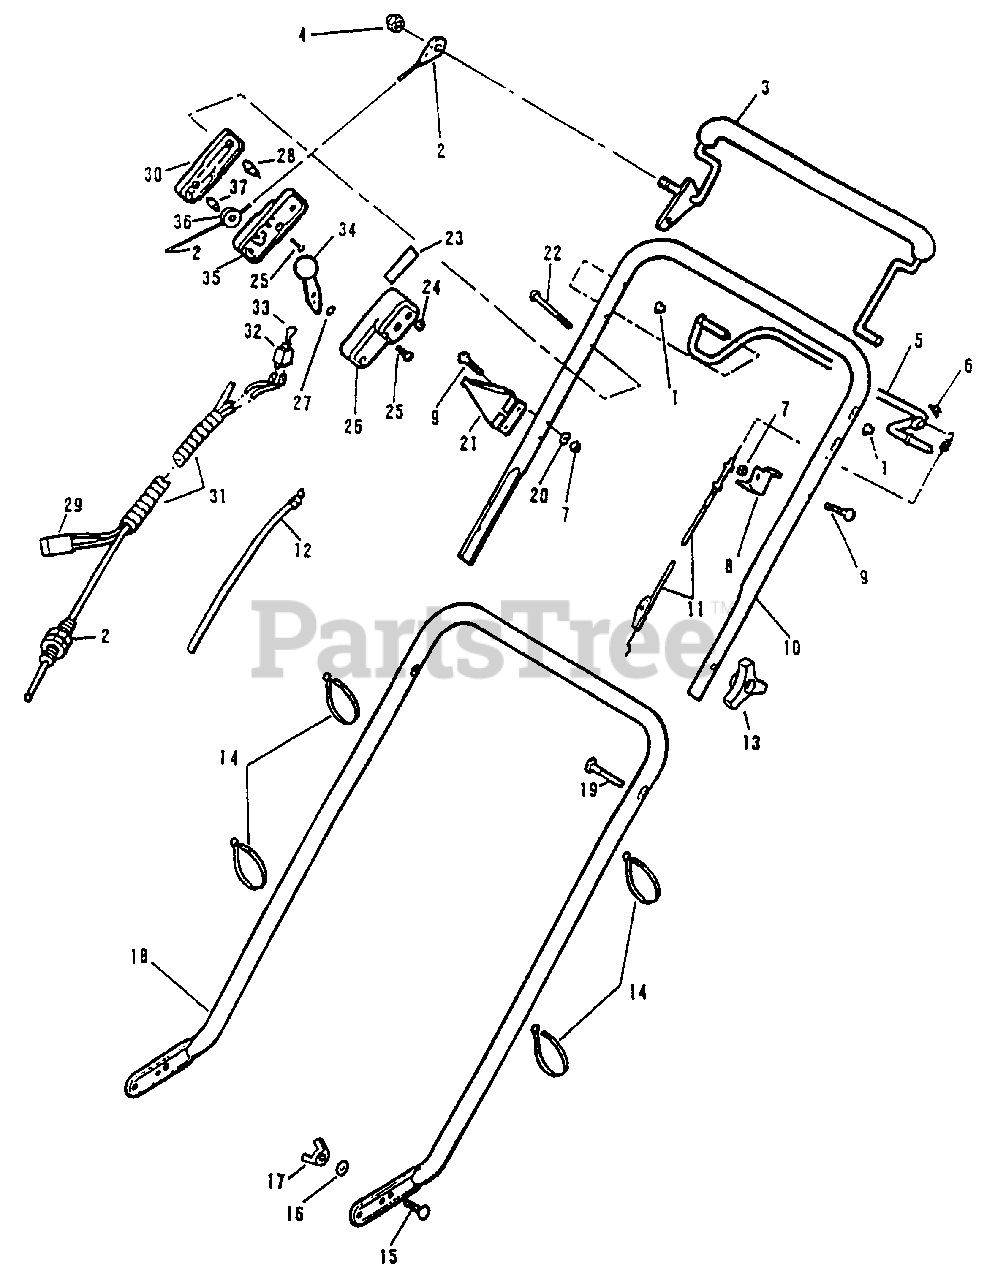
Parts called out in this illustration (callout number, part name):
1	Palnut
2	Control Cable Assembly
3	Control Lever Assembly
4	Acorn Nut
5	Control Lever-Bail
6	Nut-Push On
7	Nut
8	Conduit Anchor
9	Screw
10	Handle-Top
11	Control Cable Assembly
12	Throttle Cable
13	Handle Knob
14	Tie Strap
15	Screw-Handle Mounting
16	Washer
17	Wing Nut
18	Handle-Lower
19	Screw-Folding Handle
20	Washer
21	Rope Guide
22	Screw
23	Decal-Throttle Control
24	Nut
25	Screw
26	Case-Throttle-Inner
27	Washer
28	Column
29	Wire Harness Assembly
30	Control Case-Outer
31	Spiral Tubing
32	Switch Assembly
33	Key
34	Lever & Knob Assembly
35	Case Throttle-Center
36	Pulley
37	Pin
